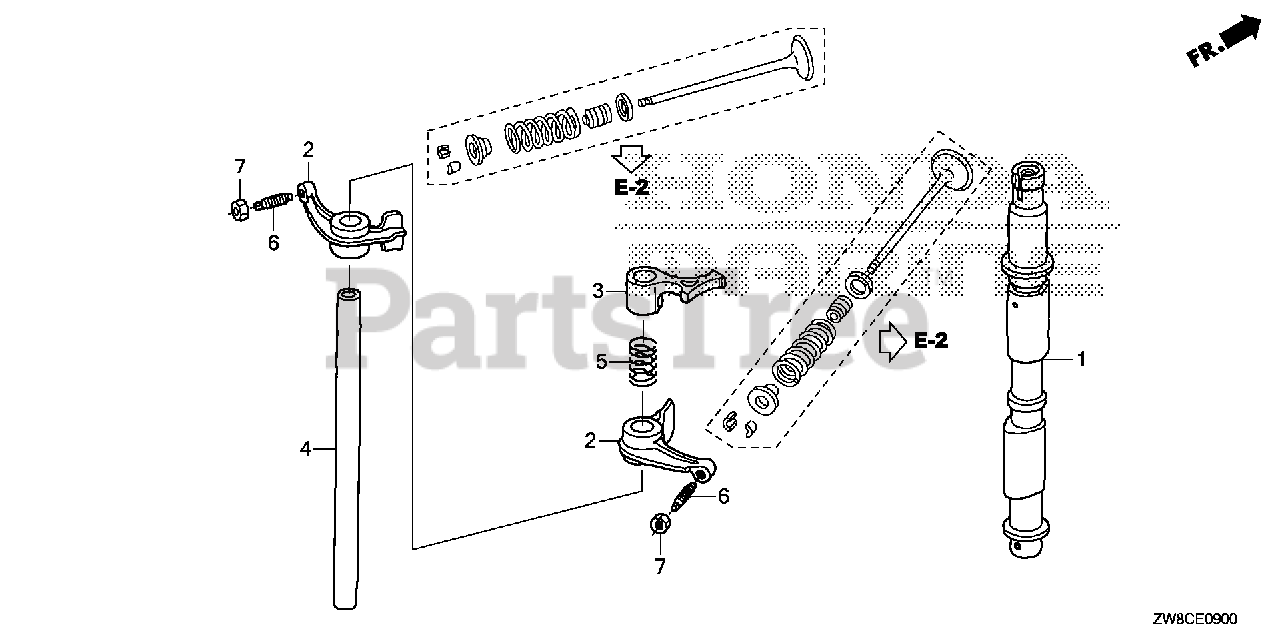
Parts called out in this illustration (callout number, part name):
2	ARM, VALVE ROCKER
3	ARM, FUEL PUMP ROCKER
4	SHAFT, ROCKER ARM
5	SPRING, ROCKER ARM
6	SCREW, TAPPET ADJ.
7	NUT, TAPPET ADJ.
